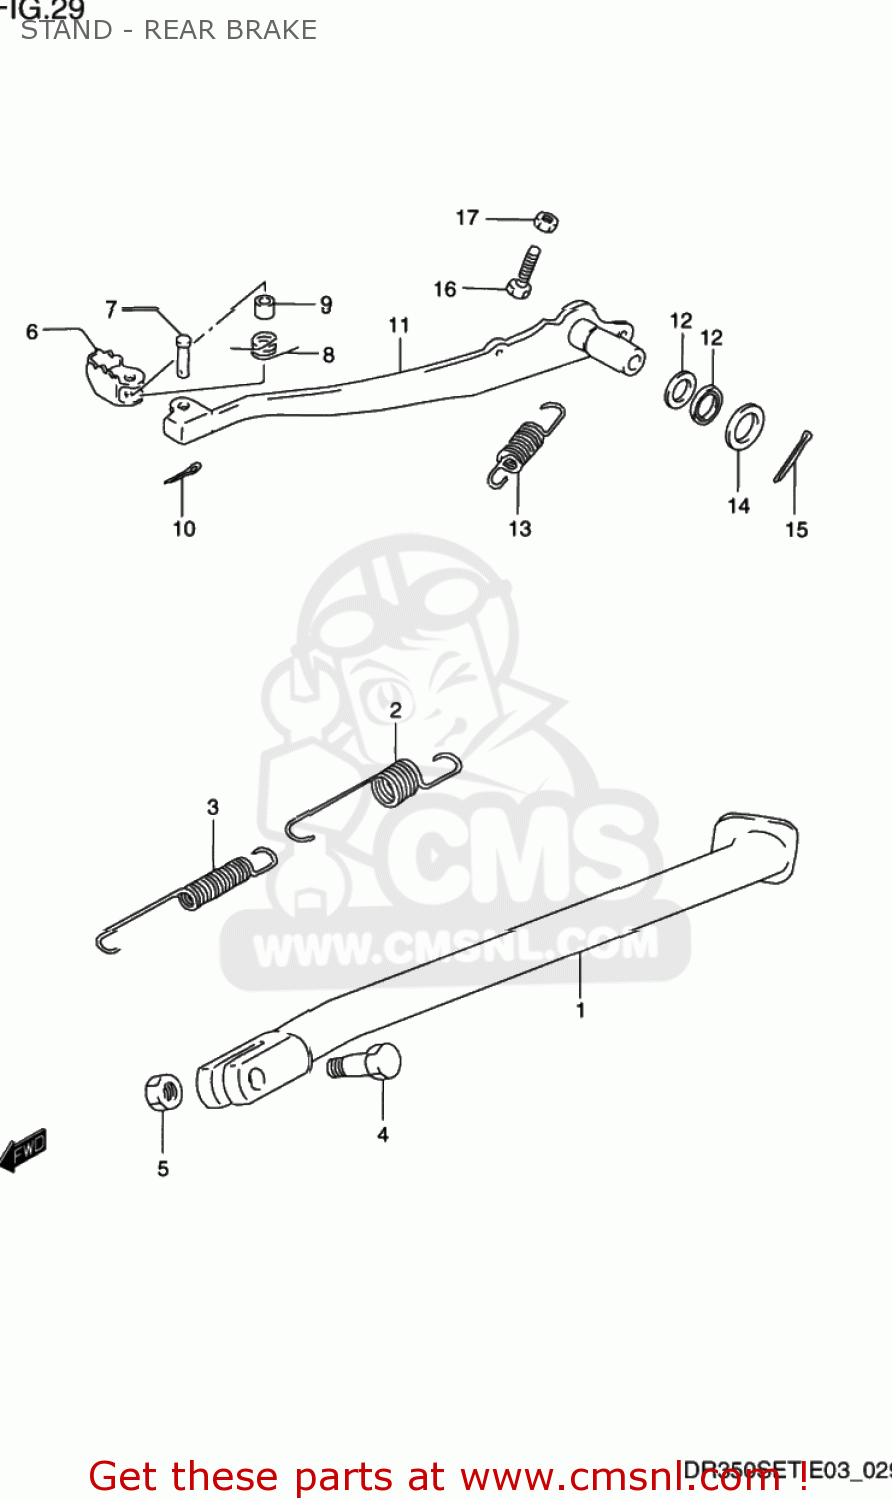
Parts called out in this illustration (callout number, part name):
1	STAND,SIDE
2	SPRING
3	SPRING
4	BOLT(10X30)
5	NUT
6	PEDAL,BRAKE
7	PIN
8	SPRING
9	SPACER(9.2X9X6.5)
10	PIN
11	ARM,BRAKE PEDAL
12	SEAL,OIL(15X21X3)
13	SPRING
14	WASHER(15.5X26X2.3)
15	COTTER PIN
16	BOLT(6X23)
17	NUT
